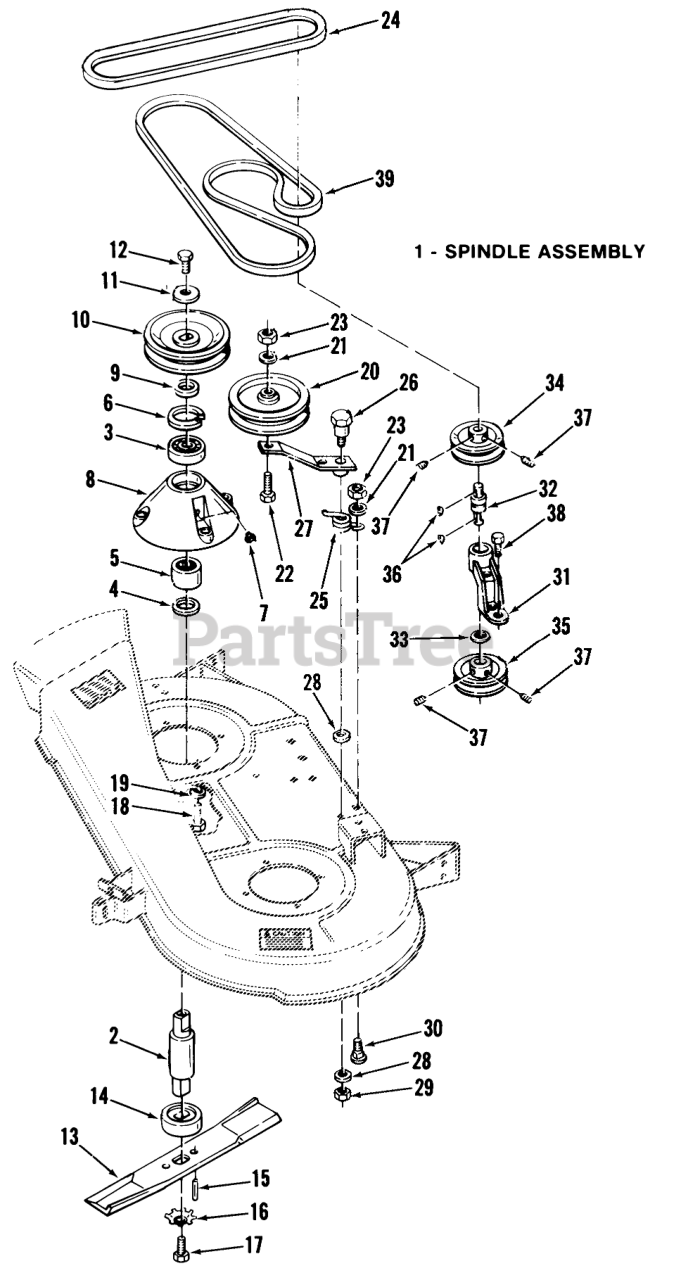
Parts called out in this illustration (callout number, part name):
1	Spindle Assembly (Includes parts 2,3,4,5,6,7,&8)
2	SPINDLE MOWER
3	BEARING-BALL
4	OIL SEAL
5	BEARING-NEEDLE
6	INT SNAP RING
7	Fitting-Grease
8	HOUSING
9	SPACER
10	PULLEY-BLADE
11	WASHER
12	Bolt
13	S/A BLADE KIT
14	Spindle Cup
15	SPIROL ROLL PIN
16	WASHER
17	Bolt
18	Bolt
19	LOCKWASHER
20	Idler Pulley
21	Washer
22	Bolt
23	Nut
24	V-BELT
25	SPRING-TORSION
26	BOLT-SHOULDER
27	Idler Arm
28	WASHER
29	Hex Nut 7/16-14
30	Bolt
31	HOUSING DRIVE BRG R
32	BEARING-INT SHAFT
33	Snap Ring
34	PULLEY
35	Pulley
36	KEY-WOODRUFF
37	Set Screw
38	Bolt
39	V BELT
